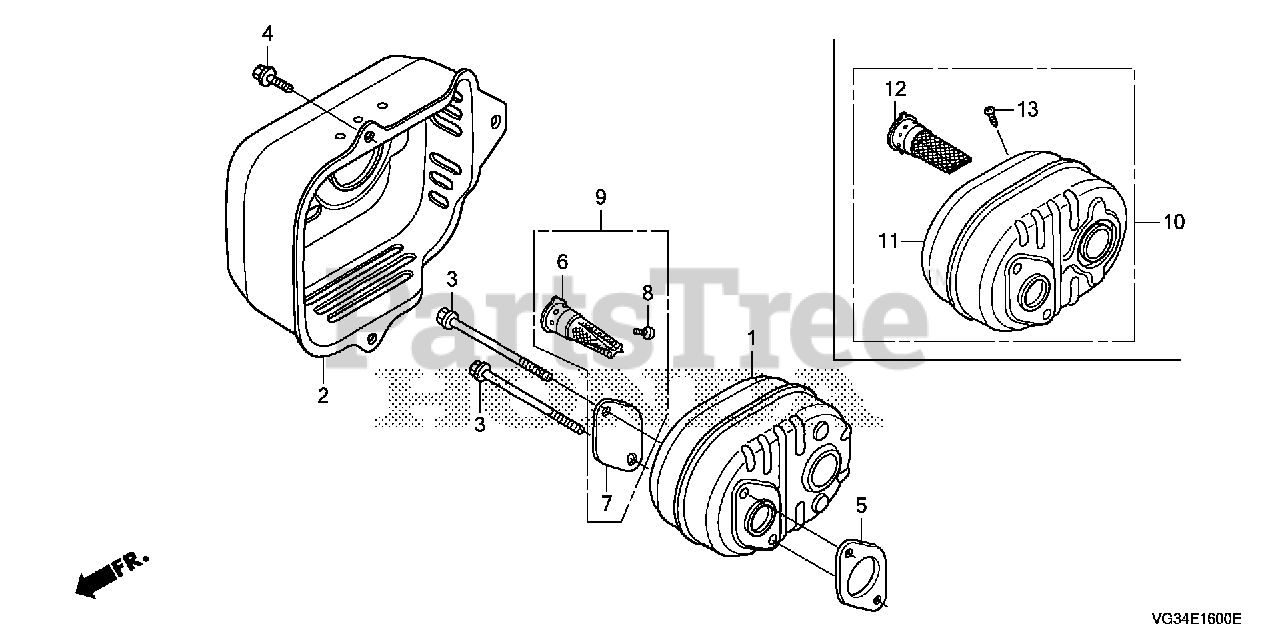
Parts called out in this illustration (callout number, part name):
2	PROTECTOR, MUFFLER
3	BOLT, FLANGE (6X79) (CT200)
4	BOLT, FLANGE (6X12) (CT200)
5	GASKET, MUFFLER
6	ARRESTER, SPARK (TO 1207644)
7	PLATE, ARRESTER NUMBER (TO INSTALL OPTIONAL SPARK ARRESTER)
8	SCREW, TAPPING (4X6) (TO INSTALL OPTIONAL SPARK ARRESTER)
9	ARRESTER KIT, SPARK
10	MUFFLER ASSY. (ARRESTER)
11	MUFFLER
12	ARRESTER, SPARK
13	SCREW, TAPPING (4X6) (TO INSTALL OPTIONAL SPARK ARRESTER)
